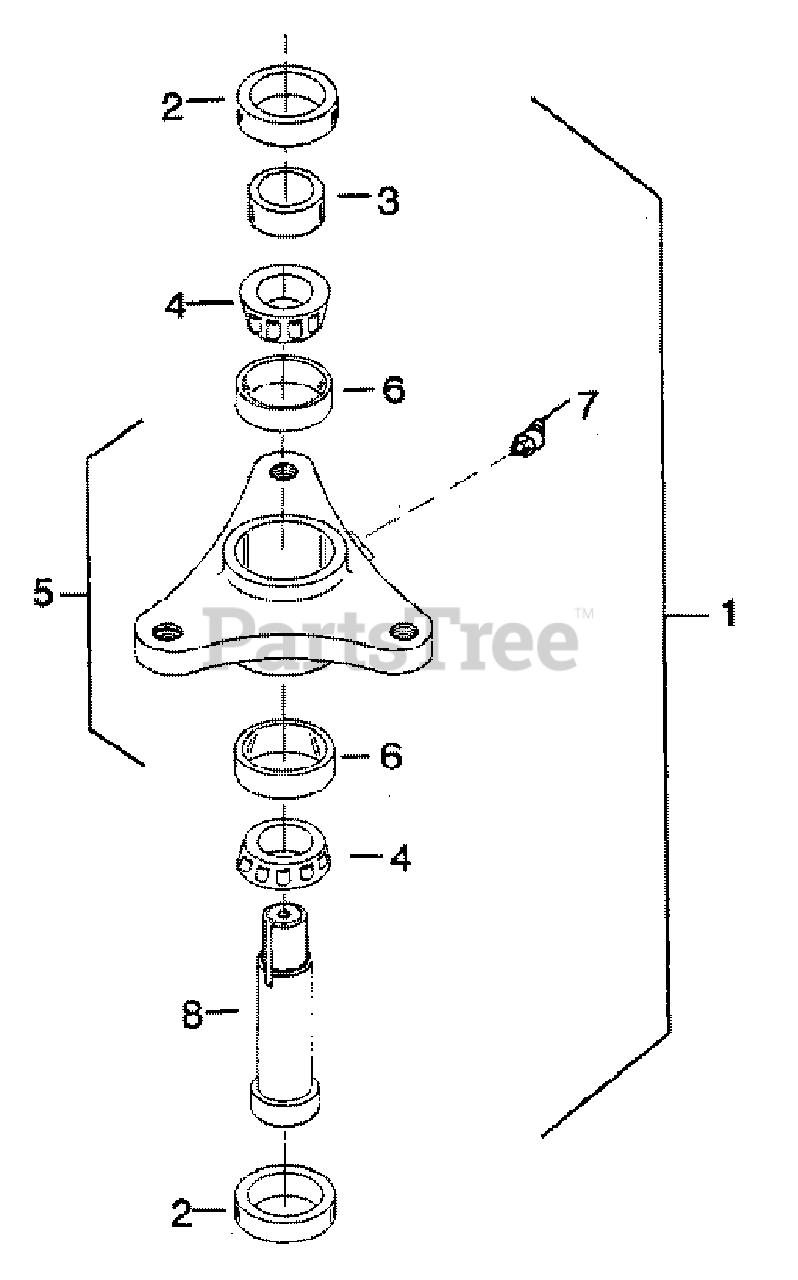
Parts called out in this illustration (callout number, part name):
1	CW Blade spindle assembly
2	Seal, 1.063 x 2.004 x .256
3	Sleeve, .84 x 1.06 x .310
4	Bearing cone #M12649
5	Spindle housing with cups
6	Bearing Cup #M12610
7	45° 1/8 Pipe thread grease fitting
8	Spindle shaft, 1.06 x 3.88-right hand threads
